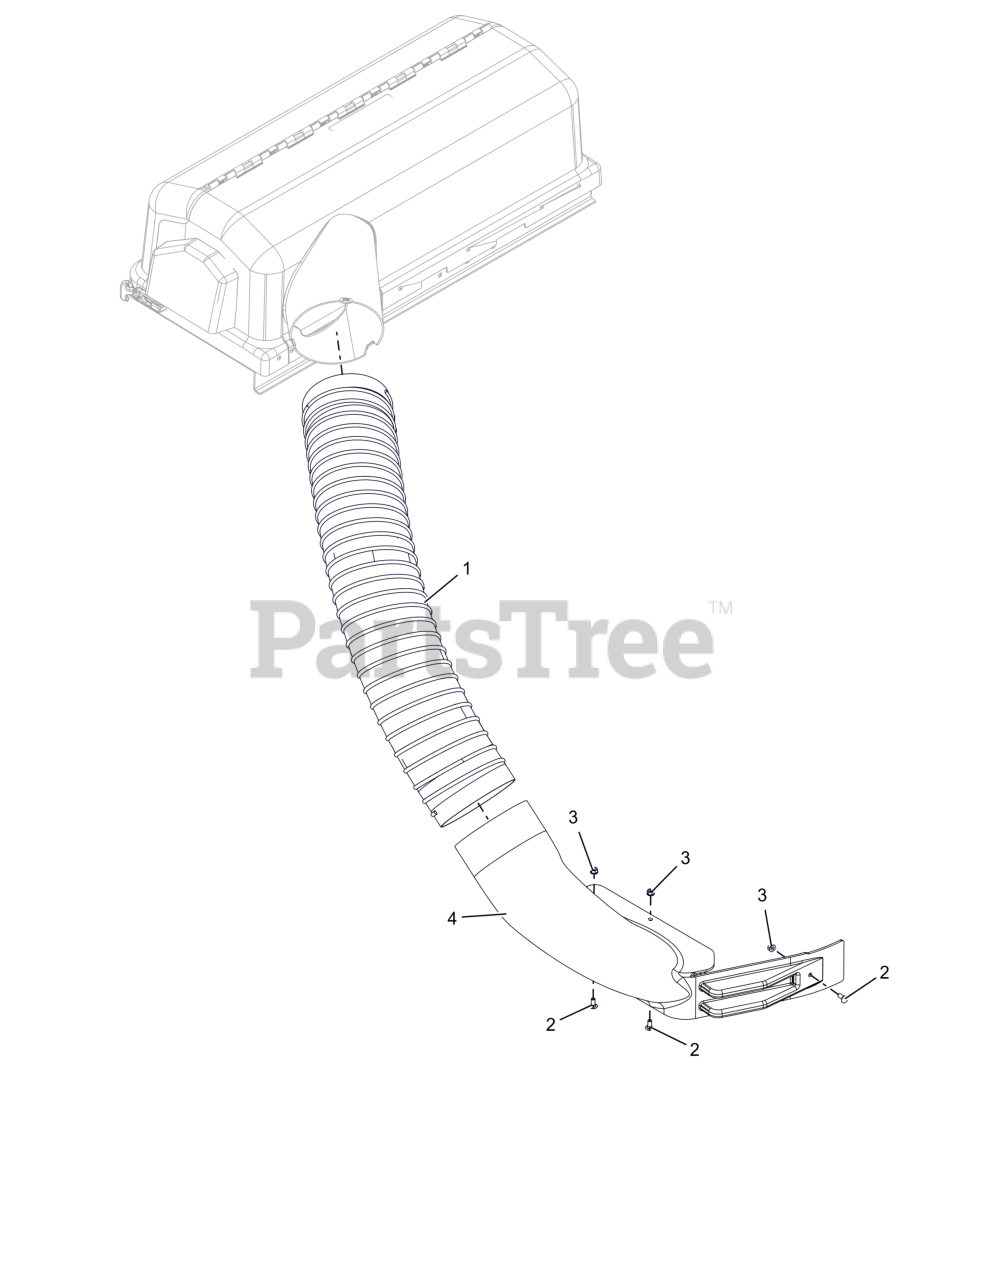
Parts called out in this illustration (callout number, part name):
1	HOSE, FLEXIBLE-47"
2	BLT,RHSN .31-18X.75 G5 ZCC
3	NUT,LK-CTR-FLG .31-18 GF ZCC
4	EDGE BAGGER NECK KIT - 42"
